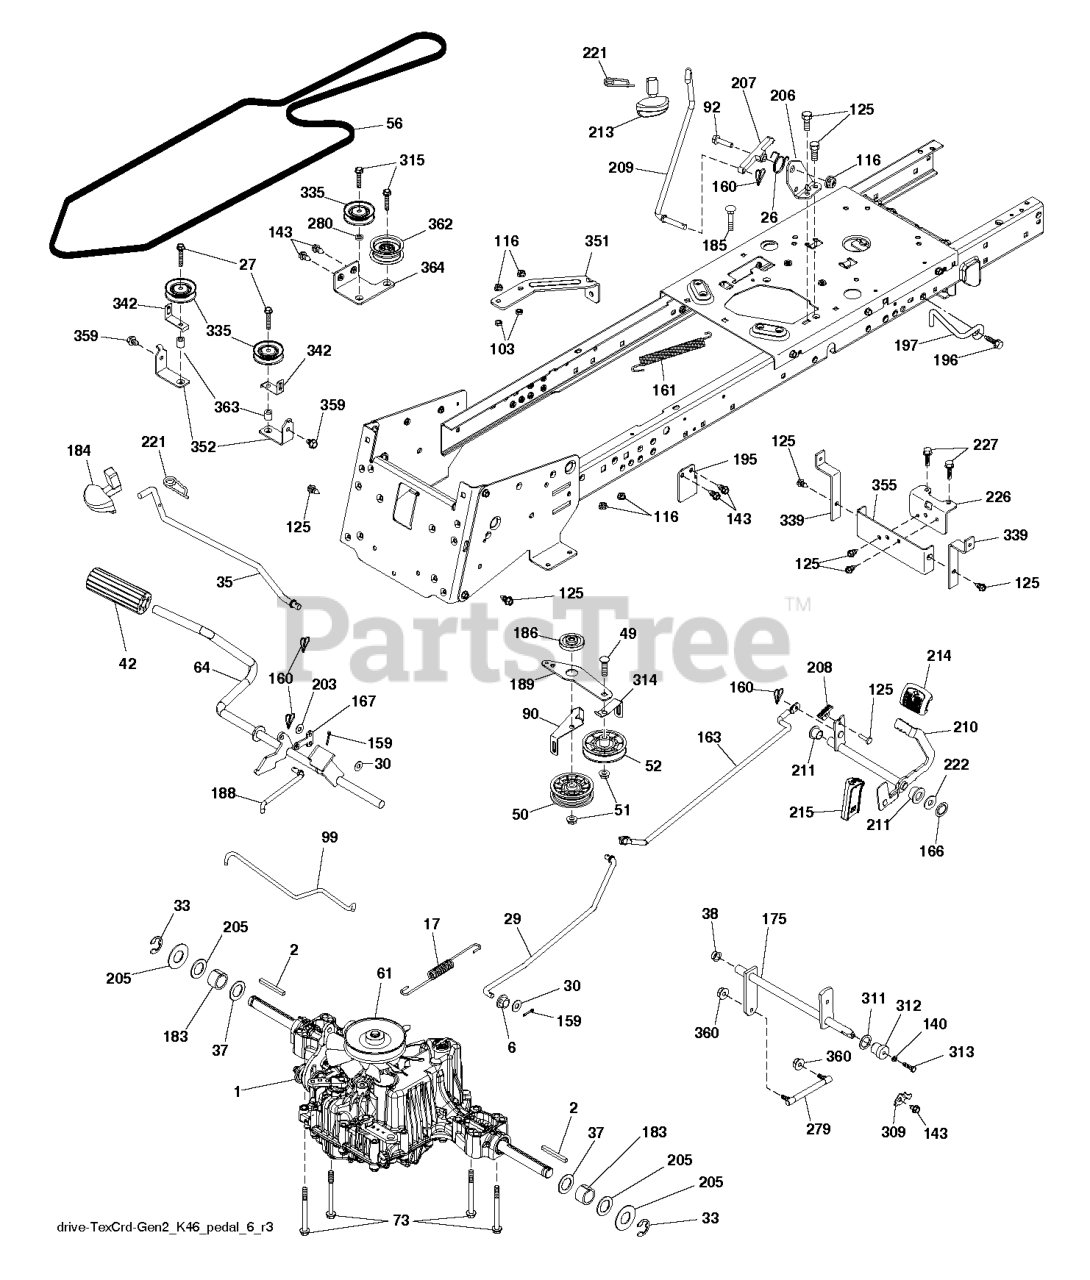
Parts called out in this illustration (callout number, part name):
2	SQUARE KEY
6	BUSHING.SNAP.NYL.BLK.
17	SPRING
26	SPRING.RETURN.CRUISE
27	SCREW
29	ROD ROD BRAKE K46 TCRD GEN 2
30	WASHER
35	ROD.BRAKE.PARTK.HUSQ.TEX
37	WASHER.HARDENED
38	NYLINER SNAP 5/8" ID
42	PEDAL COVER T
50	IDLER.FLAT.910.OFFSET
51	NUT LOCK FLG 3/8-16 UNC
52	IDLER.V-GROOVE.910.OFFSET
56	BELT BELT DRIVE GROUND 114.25
61	PULLEY PULLEY INPUT FLANGED TR
64	SHAFT.ASM.PEDAL.BRK.CNTR
73	BOLT HEX 5/16-18 GR 5
90	KEEPER KEEPER BELT CLUTCHING T
92	BOLT
99	ROD ROD BYPASS CRD TEX GEN 2
103	JAM NUT TI
116	NUT LOCK HEX FLANGE 5/16-18
125	SCREW
140	LOCKWASHER
143	SCREW LT
159	COTTER PIN
160	RETAINER CLIP
161	SPRING, RETURN LT
163	ROD ROD CONTROL SHIFT PEDAL TC
166	NUT.PUSH.625
167	LATCH.BRAKE.SPRING
175	SHAFT SHAFT CROSS SHIFT REAR F
183	SPACER AXLE
184	RB HANDLE.PARKG.BRK.HUS/PRED
186	SPACER.RETAINER
188	RP.LINK.CLUTCH.GROUND.DRIVE
189	BELLCRANK BELLCRANK GROUNDDRI
196	SCREW 3/8-16X1
197	LINK.CLUTCH.ANIT-ROTAT
203	WASHER
206	BRKT.MOUNT.LATCH.CRUIS
207	LATCH.CONTROL.CRUISE
208	GEAR.SECTOR.CONTROL.CR
209	ROD.CONTROL.CRUISE.GT.
210	ROCKER.ASM.PEDAL.CONTR
211	BEARING.NYLON
213	KNOB.CONTROL.CRUSIE.HU
214	PEDAL.FORWARD.PAD.TEX
215	PEDAL RUBBER REVERSE
221	RETAINER.SPRING.CLIP.H
222	WASHER 21/32 X 1-1/4 X 10 GA.
226	BRACKET.MOUNT.TORQUE.K46.TLT
227	SCREW.THDROL.5/16-18X3/4.TTY
279	LINK SUBASM. LINK AND STUD
280	WASHER T
309	PLATE.FASTENING.CROSS.SHAFT
311	WASHER NYL
312	HUB.TAPERED.ROUND.CRD
313	BOLT
314	RETAINER KEEPER BELT
315	BOLT.5/16-18X1.25
335	PULLEY.V-IDLER.
339	STRAP STRAP TORQUE K46 CRD TE
342	BELT GUIDE
351	BRACKET BRACKET DECK SWAY
352	BRACKET BRACKET IDLER CRD TEX
355	STRAP STRAP TORQUE K46 CRD TEX
359	SCREW LT
360	NUT NUT HEX CENTERLOCK 5/16-24
362	IDLER.FLAT.2.25.INCH
363	SPACER SPACER 343X63X.62
364	BRACKET BRACKET IDLER CRD TEX
